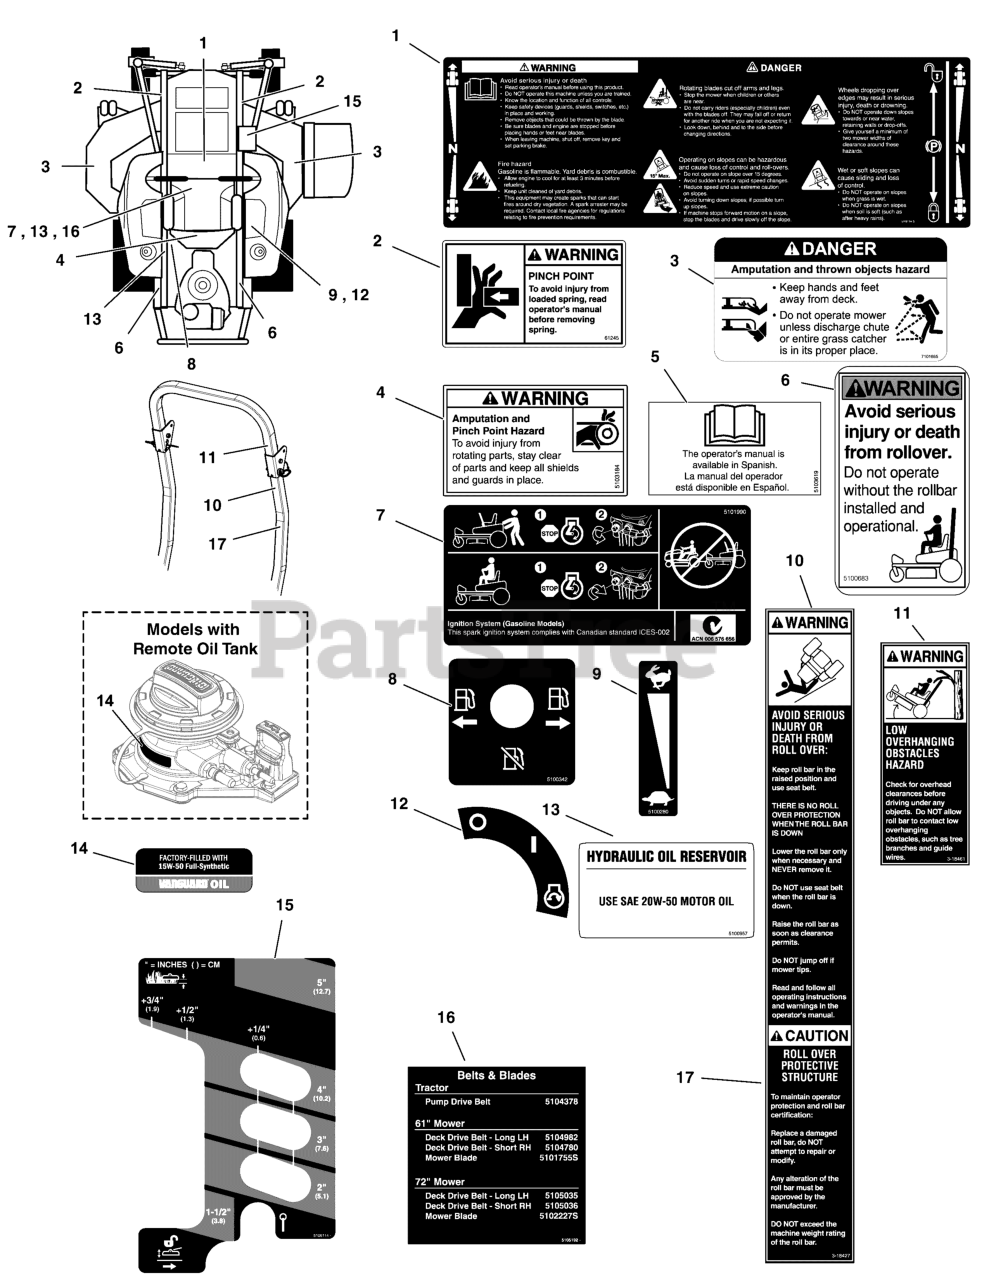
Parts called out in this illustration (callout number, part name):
1	DECAL, MAIN SAFETY
2	DECAL, PINCH POINT
3	DECAL, DANGER DO NOT OPERATE W/O DEFLECT
4	DECAL, WARNING, HAND IN BELT, ENG ONLY
5	DECAL, MANUAL AVAIL IN SPANISH
6	DECAL, WARNING, ROLL BAR
7	DECAL, TRANSAXLE RELEASE, S200XT
8	DECAL, FUEL VALVE
9	DECAL, THROTTLE CONTROL
10	DECAL, WARNING, FOLDING ROPS
11	DECAL, WARNING OVERHANG, ROPS (SV)
12	DECAL, IGNITION SWITCH
13	DECAL, HYDRAULIC OIL, 20W50
14	LABEL, OIL INFORMATION
15	DECAL, CUTTING HEIGHT
16	DECAL, BELT & BLADE IS3200Z 2BELT
17	DECAL, CAUTION, FOLDING ROPS
